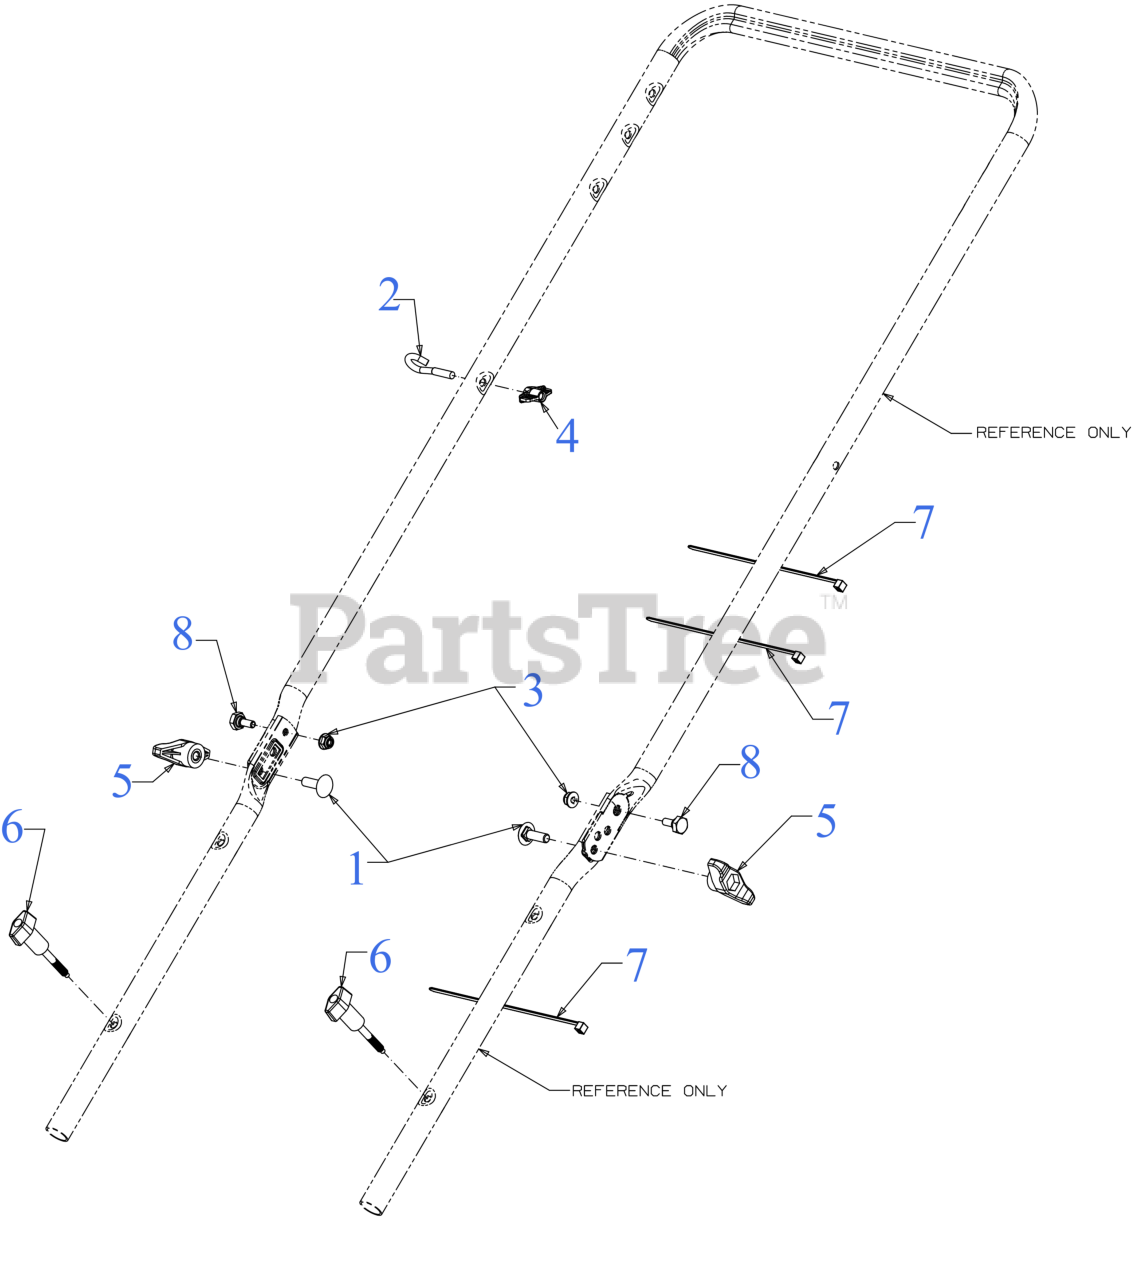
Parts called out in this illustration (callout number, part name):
1	SCREW 5/16-18 x 1.00 GR5
2	EYEBOLT 1/4-20
3	FLANGE LOCK NUT
4	HANDLE KNOB
5	WING KNOB 5/16-18
6	WING KNOB 1/4-20
7	7" CABLE TIE
8	SHOULDER SCREW
